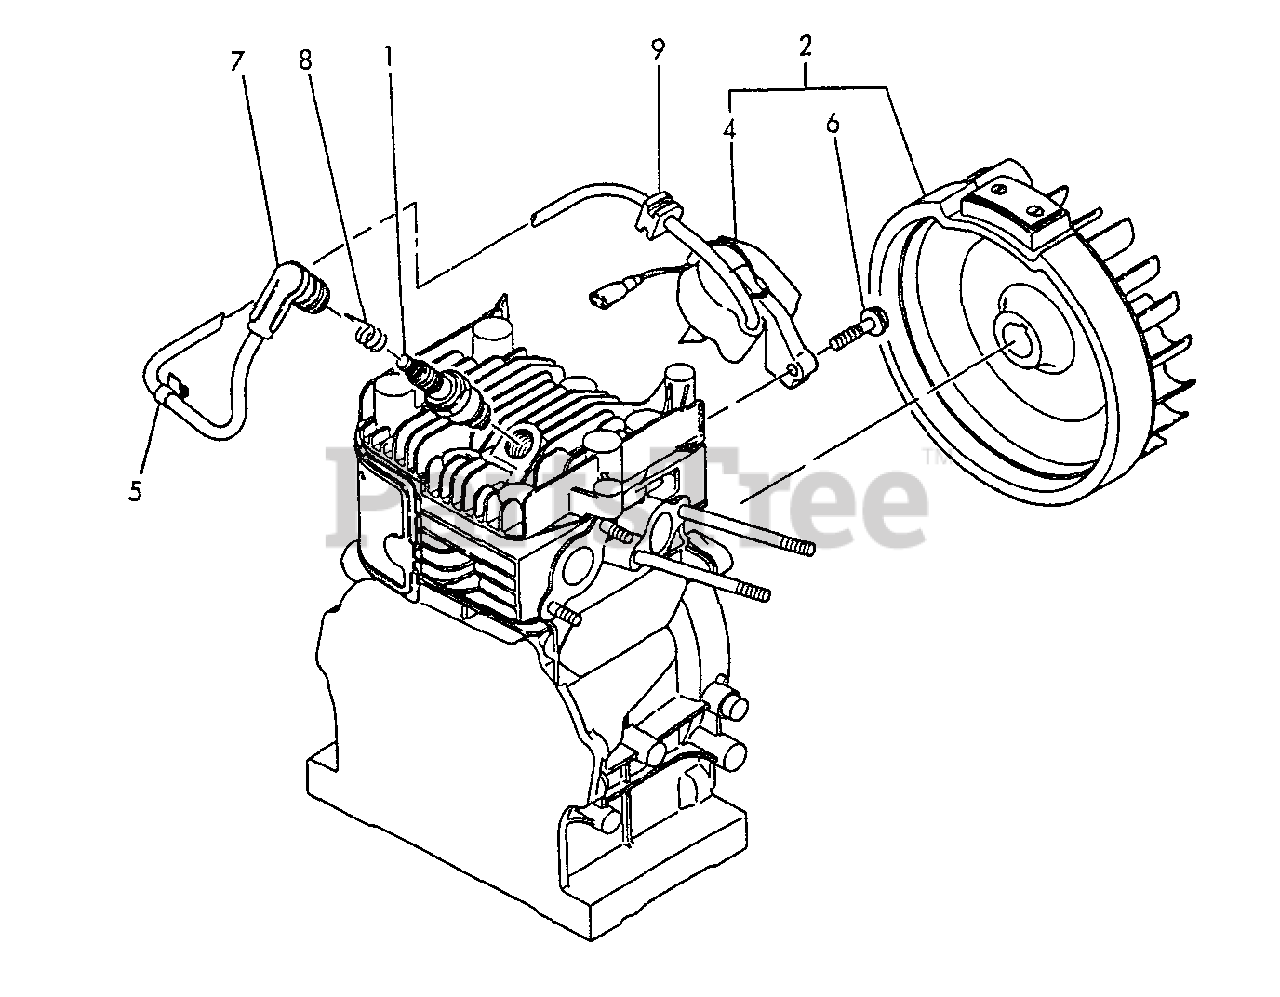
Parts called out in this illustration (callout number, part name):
1	SPARK PLUG
2	FLYWHEEL
4	COIL, IGNITION
5	CLAMP
6	BOLT - 6X25
7	CAP, PLUG
8	TERMINAL, SPARK PLUG CAP
9	GROMMET
